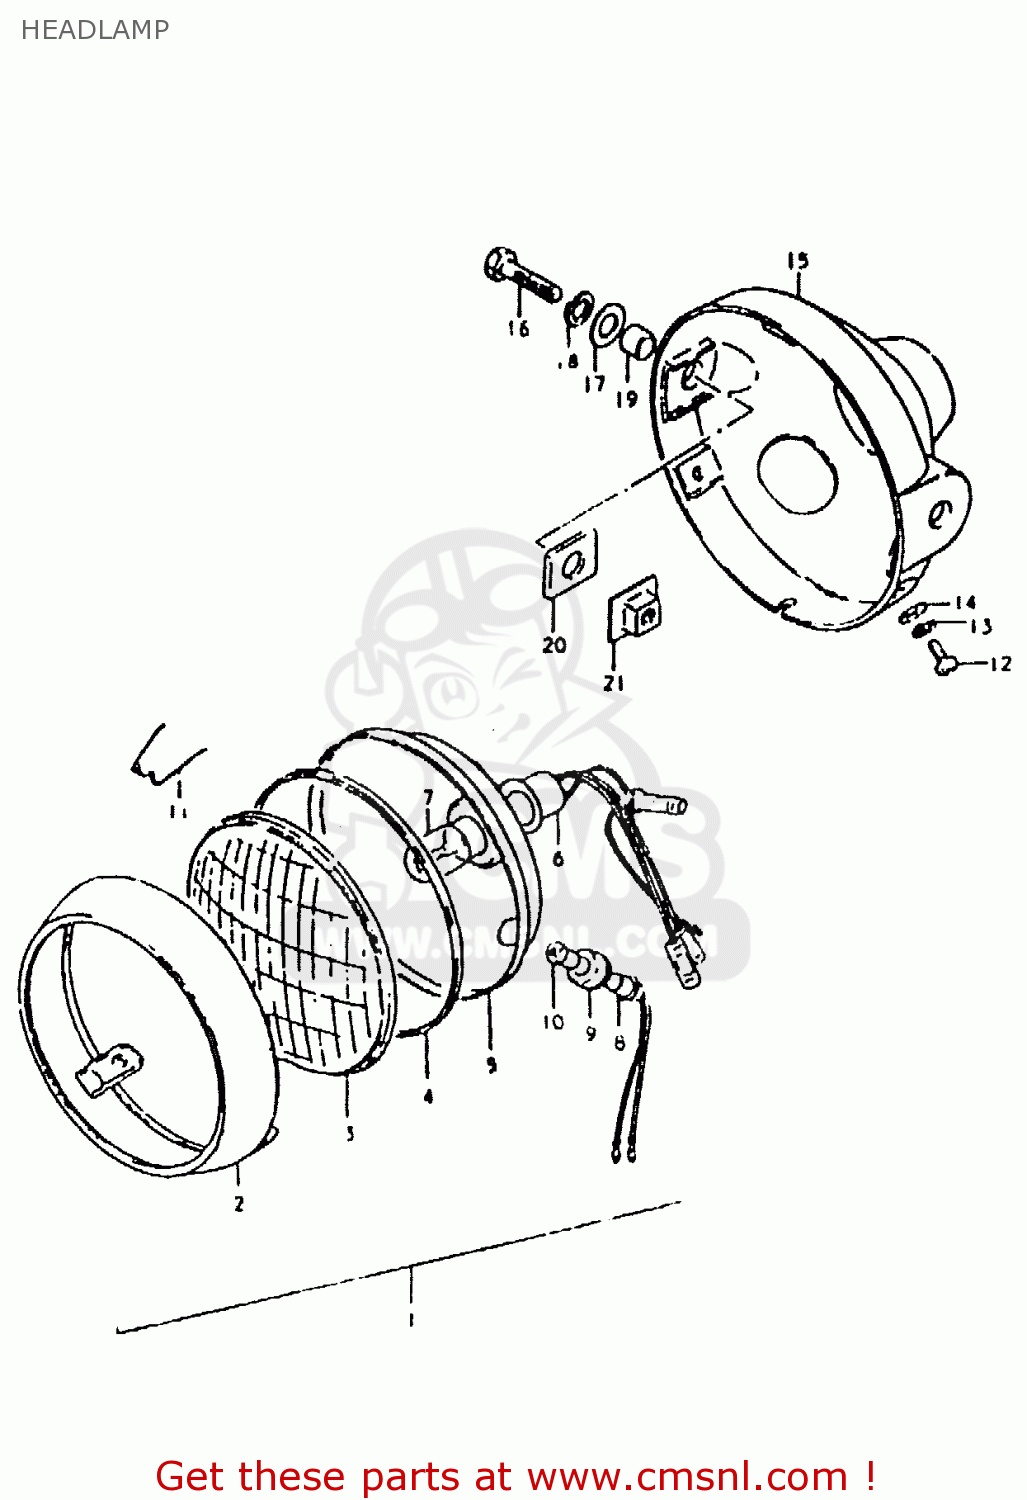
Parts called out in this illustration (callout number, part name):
1	HEADLAMP
2	RIM,HEADLAMP
3	LENS
4	GASKET (NAS)
5	REFLECTOR
6	SOCKET
7	BULB (7V,18/18W)
8	SOCKET
9	JOINT,RUBBER
10	BULB(6V/3W)
11	SPRING
12	SCREW
13	LOCK WASHER
14	WASHER
15	HOUSING,HEADLAMP
16	BOLT
17	WASHER
18	LOCK WASHER
19	SPACER (8.8X12X7)
20	CUSHION
21	PLATE,HEADLAMP HOUSING
